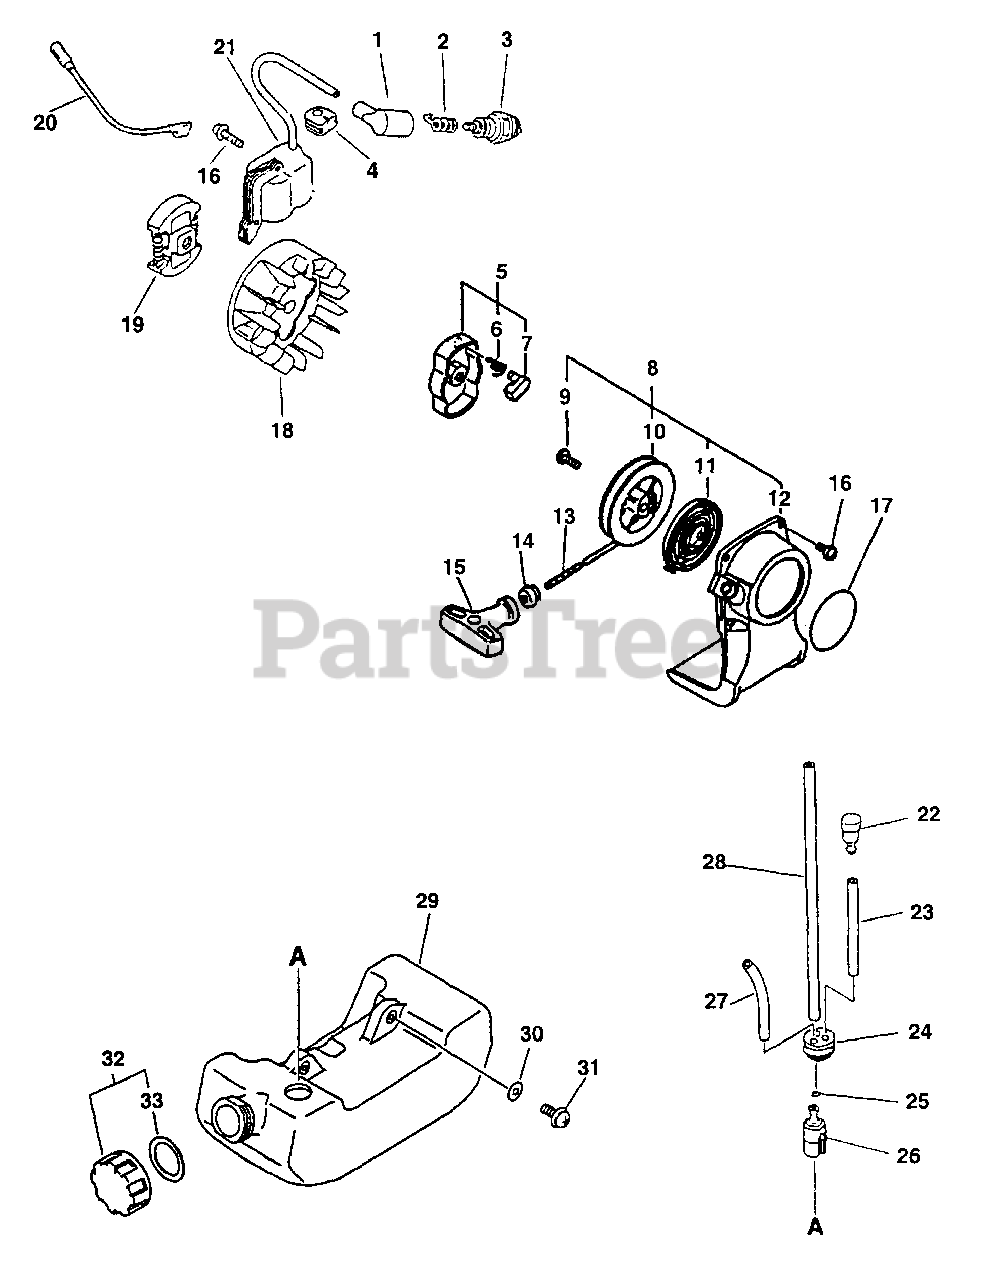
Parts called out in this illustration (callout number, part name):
1	CAP, SPARK PLUG
2	TERMINAL, SPARK PLUG CAP
3	SPARK PLUG -- BPM-7A
5	STARTER PAWL ASSY
6	SPRING, RETURN
7	PAWL, STARTER - BLACK
8	STARTER ASSY
10	REEL, ROPE
11	SPRING, REWIND
12	CASE, STARTER - BLUE
13	ROPE, STARTER - 3X890
14	GUIDE, ROPE
15	GRIP, STARTER
16	SCREW - 4X22
17	LABEL - ECHO
18	FLYWHEEL
19	CLUTCH ASSY
20	LEAD - IGNITION
21	COIL, IGNITION
22	VENT, FUEL TANK
23	PIPE - 3X5X70 -- BLACK
24	GROMMET
25	CLIP - 6
26	FILTER, FUEL
27	PIPE - 3X6X90 -- CLEAR
28	PIPE - 3X5X180 -- BLACK
29	FUEL TANK ASSY
30	WASHER - 5
31	SCREW - 5X16
32	CAP ASSY
33	GASKET, CAP
